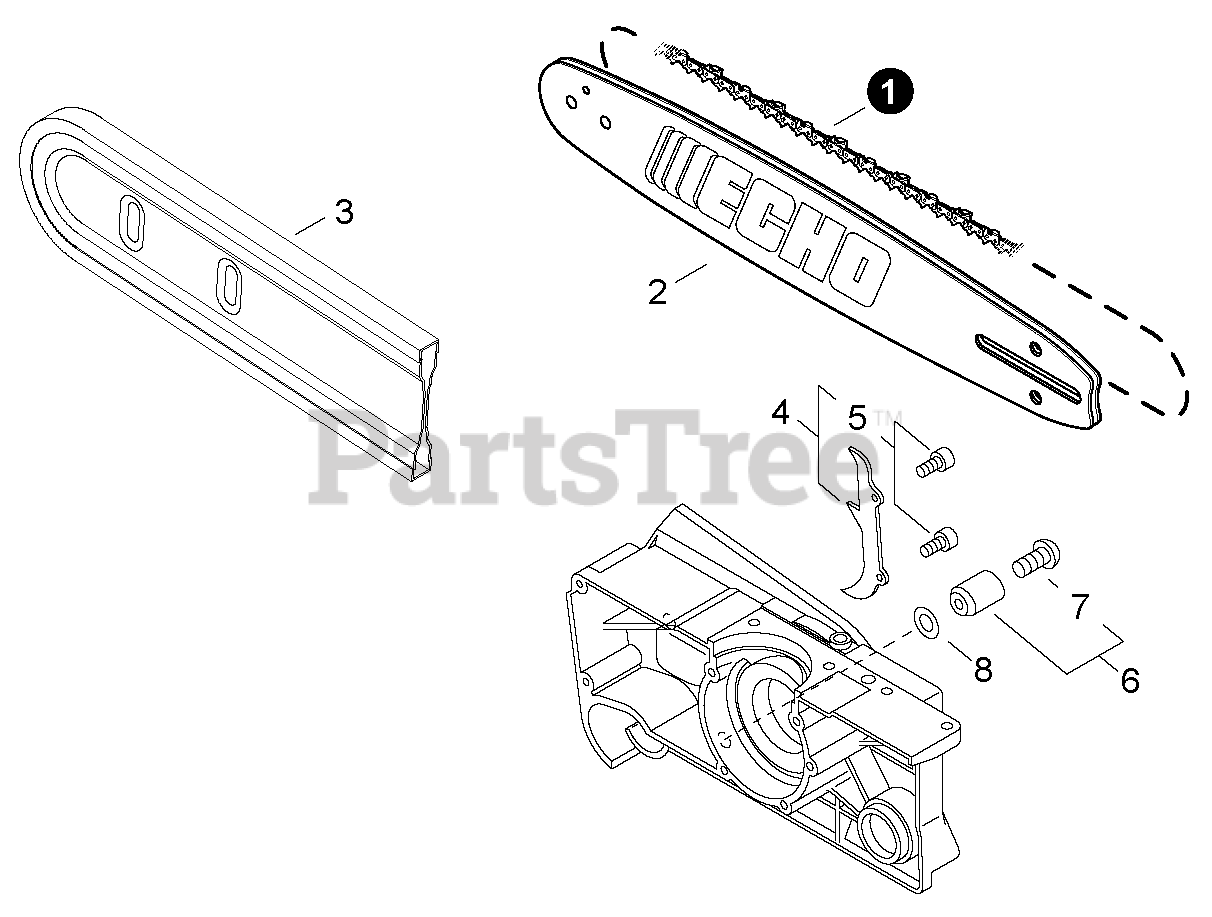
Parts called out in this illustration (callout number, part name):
1	SAW CHAIN 20"
1	SAW CHAIN 24"
1	SAW CHAIN 28"
2	GUIDE BAR, 20" ARMOR TIP
2	GUIDE BAR, 24" ARMOR TIP
2	GUIDE BAR, 28" ARMOR TIP
3	SCABBARD
4	SPIKE KIT, BUMPER
5	BOLT 5×12
6	CHAIN CATCHER KIT
7	SCREW 5×18
8	WASHER, FLAT 5.5×10×0.8
